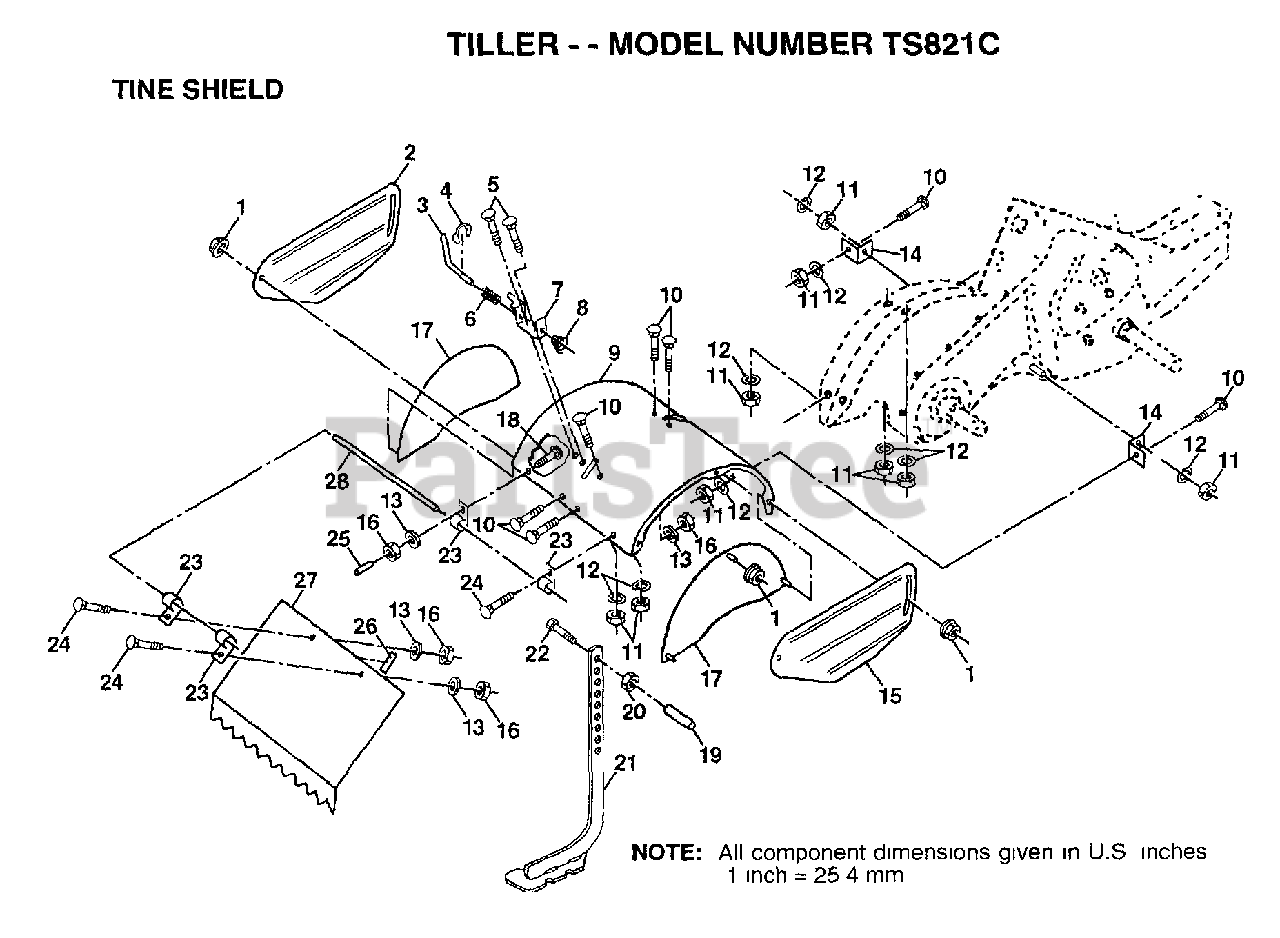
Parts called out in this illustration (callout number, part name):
1	NUT
2	SHIELD SIDE OUT L
3	STAKE PIN TI
4	KLIP RING TI
5	BOLT
6	SPRING TI
7	LATCH BRACKET TI
8	SPRING CRT
9	SHIELD TINE RED
10	BOLT
11	NUT.HEX.5/16-18
12	LOCKWASHER
13	LOCKWASHER
14	TINE SHLD BRKT TI
15	SHIELD SIDE RH
17	SHIELD SIDE RED
18	BOLT
19	GRIP CRT
20	NUT.HEX.3/8-16UNC
21	STAKE.ASM.DEPTH
22	BOLT
23	HINGE CRT
24	BOLT.1/4-20X1/2
25	VINYL CAP TI
26	PAD IDLER TI
27	SHIELD LEVELING
28	PIN.HINGE
